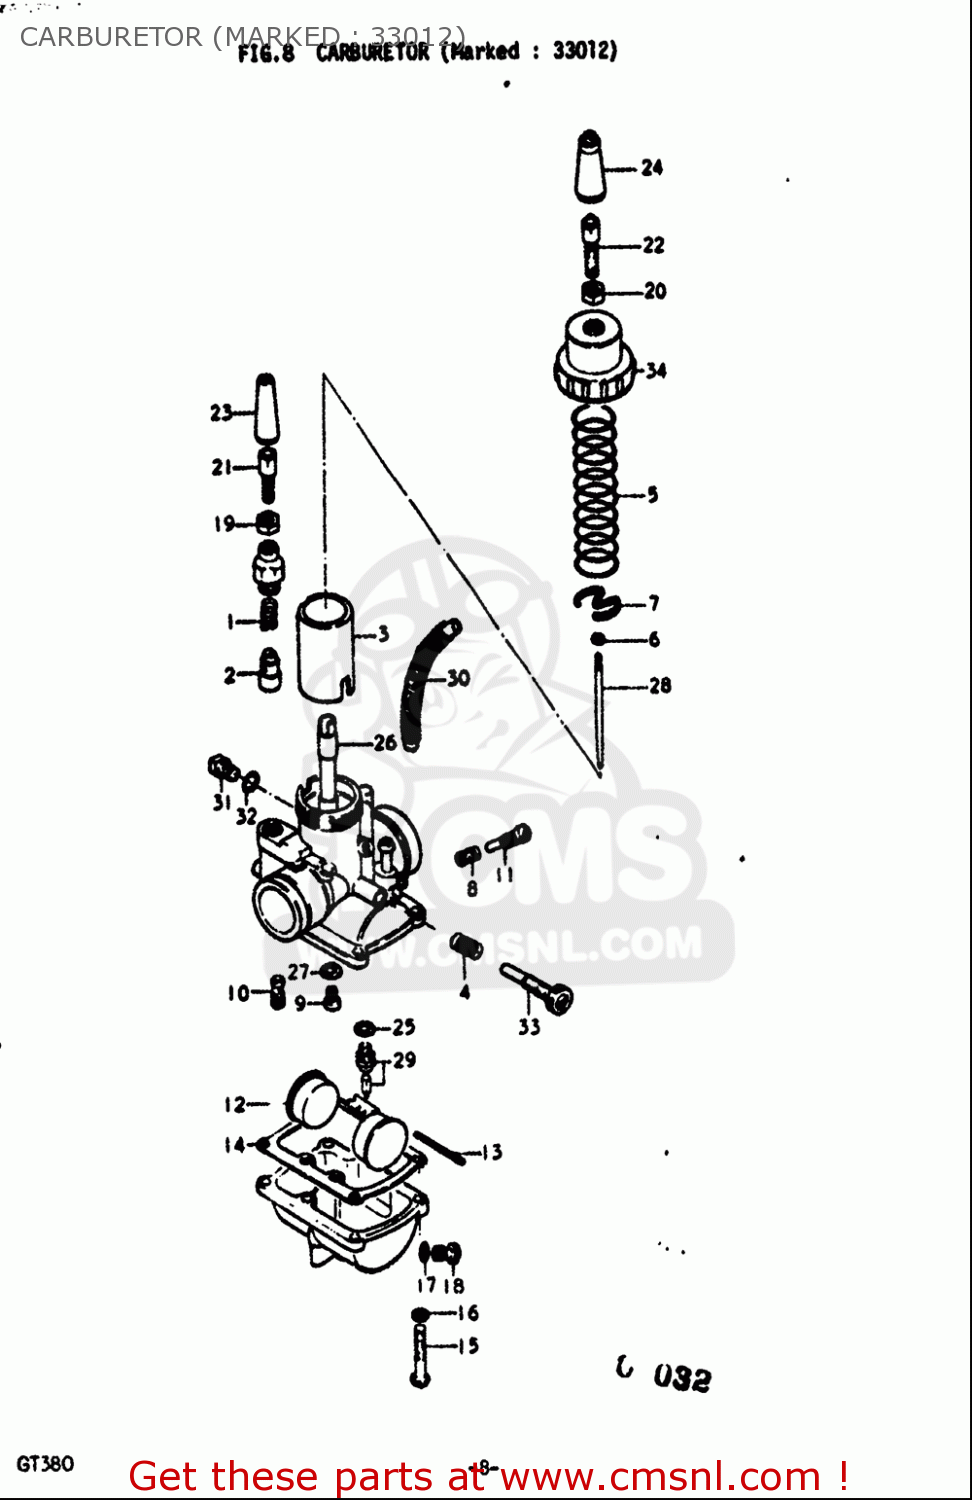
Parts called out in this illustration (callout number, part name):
1	SPRING
2	PLUNGER,STARTER
4	SPRING
6	CLIP
7	SEAT,THROTTLE VALVE SPRING
8	SPRING
9	JET,MAIN
10	JET,PILOT(22.5)
11	SCREW,PILOT AIR ADJUSTING
12	FLOAT
13	PIN,FLOAT
14	GASKET,FLOAT CHAMBER (NAS)
15	SCREW 4X16
16	WASHER,LOCK
17	GASKET,DRAIN,PLUG (NAS)
18	PLUG
19	NUT
21	ADJUSTER,CABLE
23	CAP
25	GASKET,VALVE SEAT (NAS)
27	WASHER
28	NEEDLE,JET
29	VALVE ASSY,NEEDLE
31	BOLT
32	GASKET,THRO VALVE INSPECTION (NAS)
